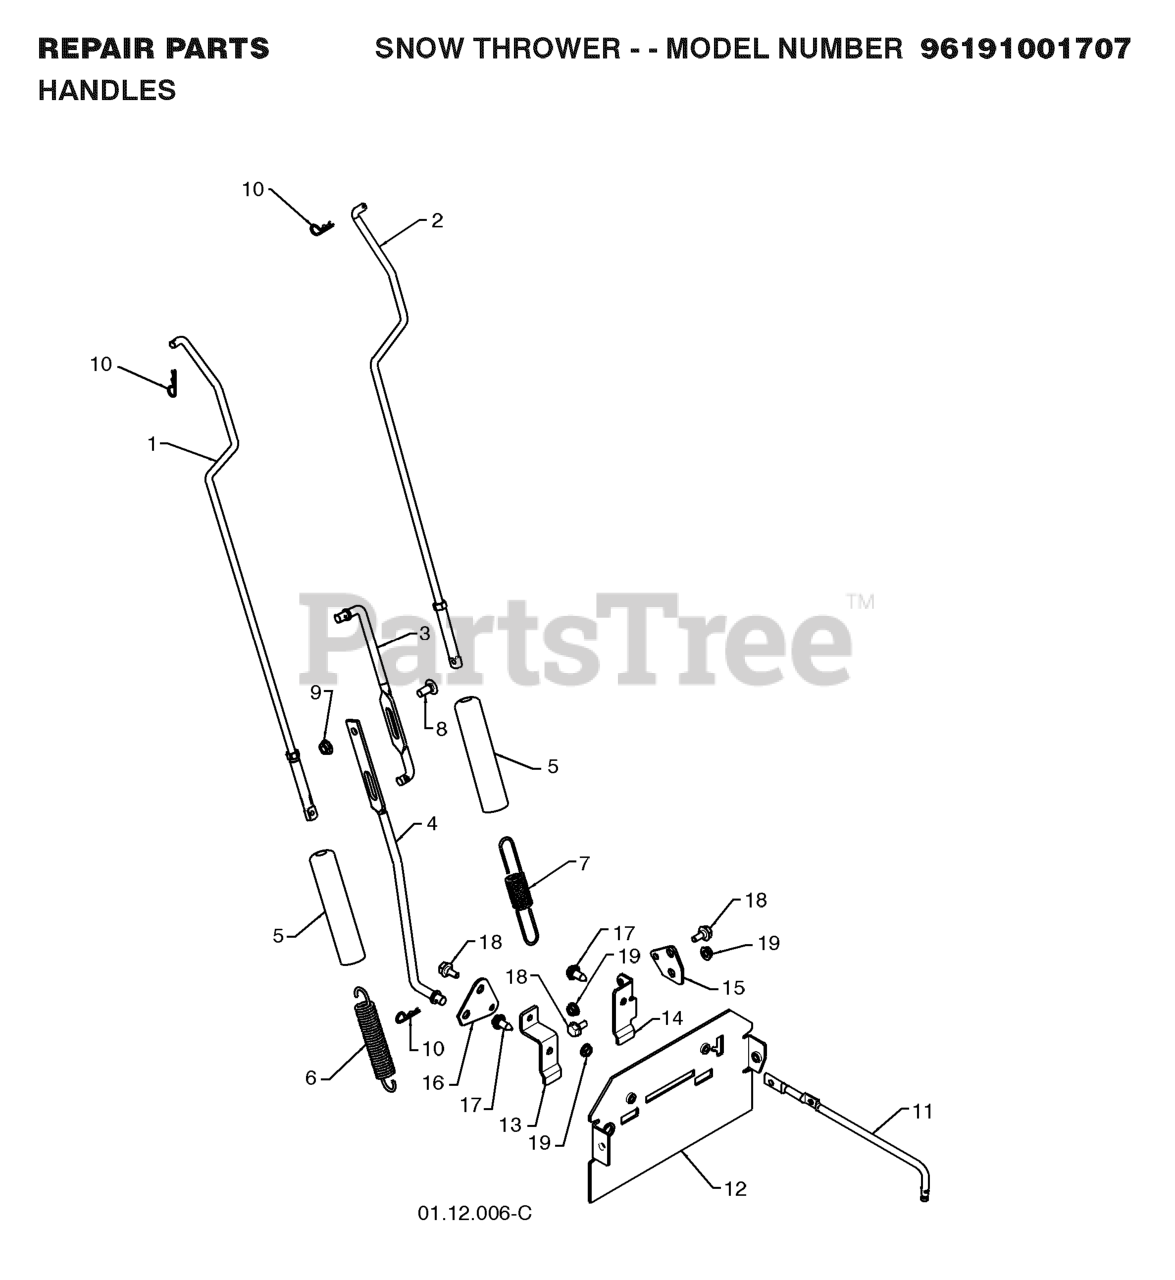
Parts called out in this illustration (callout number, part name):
1	ROD.ASM.IMPELLER
2	ROD.ASM.TRACTION
3	ROD, UPPER SPEED CONTROL
4	ROD, LOWER SPEED CONTROL.SNOW
5	SLEEVE, SPRING
6	SPRING, AUGER CONTROL
7	SPRING, TRACTION DRIVE
8	BOLT
9	NUT.FLANGE.5/16
10	SPRING RETAINER
11	ROD.CLUTCH.YELLOW.ZINC(VT)
12	PLATE.REAR.SNOW.PNT.ORANGE
13	BRACKET.SHIFTER.PLATE.BZP
14	BRACKET.CLUTCH.PLATE.BZP
15	PLATE.CLUTCH.BZP
16	PLATE.SHIFTER.BZP
17	SELF-TAPPING SCREW 5/16-18X3/4
18	BOLT.SHOULDER.3/X.25
19	NUT.HEX.FLANGE.1/4
